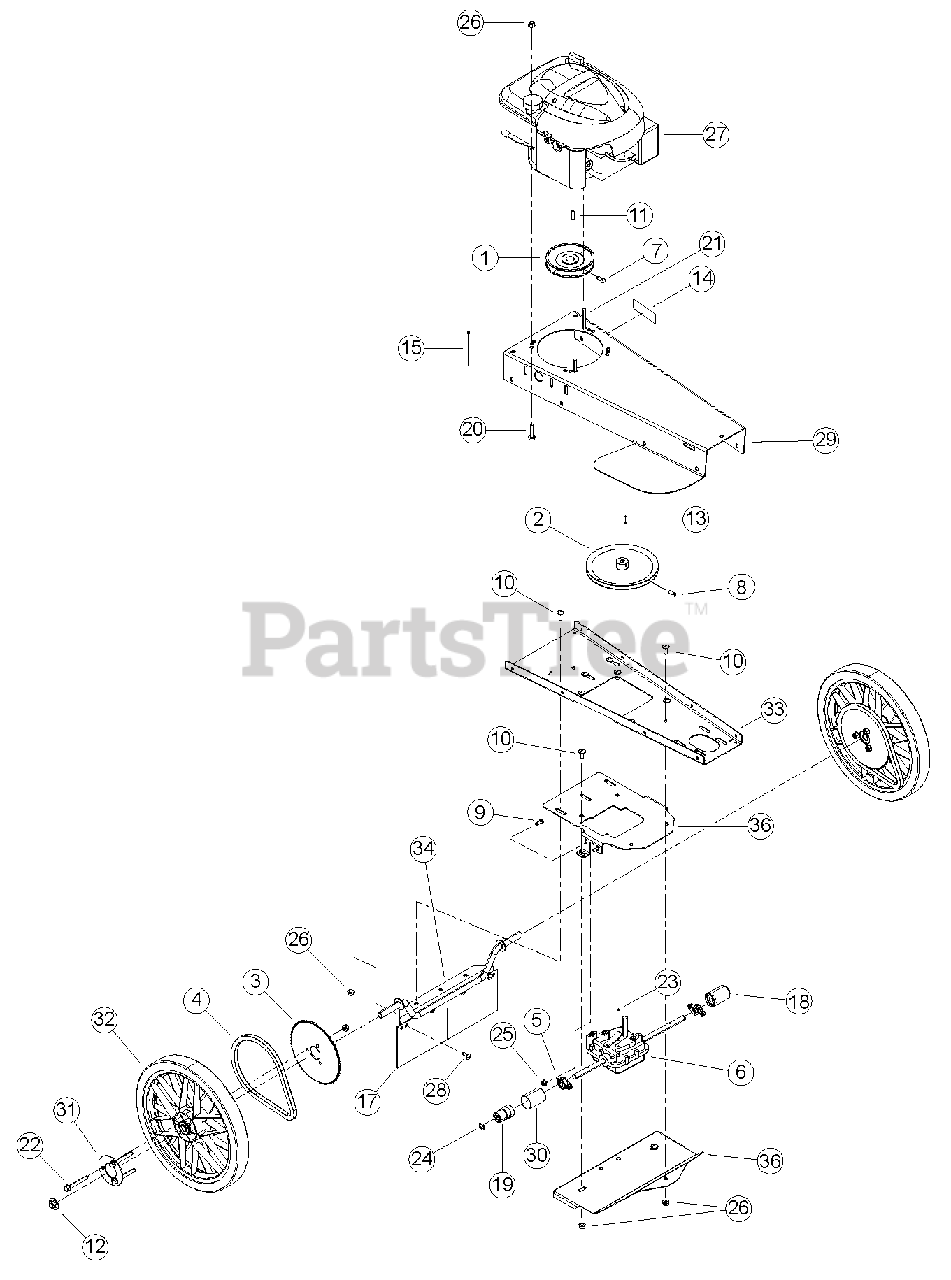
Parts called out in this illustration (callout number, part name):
1	PULLEY, 5.0 X 7/8 AB
2	PULLEY, 7-1/2 X 12MM A GROOVE
3	SPROCKET, 35A60 W/HOLES
4	CHAIN, EZ TRIMMOWER
5	BEARING, 1/2 FLANGE
6	TRANSMISSION, 3 SPEED SEE BULLETIN SIB 14 001
7	SCREW, 5/16-18 X 5/8 SQ HD SET
8	SET SCREW, 1/4 X 5/8 SQ HD
9	BOLT, CARR 1/4 X 3/4 GR5 ZP
10	BOLT, CARR 5/16*7/8" GR5 NC ZP
11	SQUARE KEY, 3/16" X 1.00"LG
12	PUSHNUT, 5/8" ZP
13	KEY, 4MM SQ X 20 MM
14	DECAL, SERIAL NUMBER
15	STRAP, 4 IN BLACK
17	FLAP, TRIMMER
18	WELDMENT, LH WHEEL CLUTCH
19	WELDMENT, RH WHEEL CLUTCH
20	BOLT, 5/16 X 1-1/2 FLANGE NC
21	BOLT, 5/16 X 2-1/2 FLANGE NC
22	BOLT, 5/16 X 2-3/4 FLANGE NC
23	SCREW, #8-32 X 3/16 KNR CUP PT
24	CLIP, 1/2" E
25	NUT, 1/4-20 NYLOCK FLANGE
26	NUT, 5/16-18 NYLOCK FLANGE
27	ENGINE, 6.5 HP QUANTUM HD 50 STATE (FOR SERVICE SEE ENGINE OWNER'S MANUAL OR YOUR NEAREST AUTHORIZED BRIGGS & STRATTON INDUSTRIAL ENGINE DEALER.)
28	RIVET, PLASTIC 1/4 X 7/8
29	BODY, TRIMMER
30	TUBE, 1.5" X 2.125" HEAT SHRINK
31	SHEET, CAP WHEEL
32	ASSEMBLY, TRIMMER WHEEL
33	BOTTOM, TRIMMER FRAME
34	WELDMENT, TRIMMER AXLE
35	PAN, TRIMMER BOTTOM
36	PLATE, TRANSMISSION
